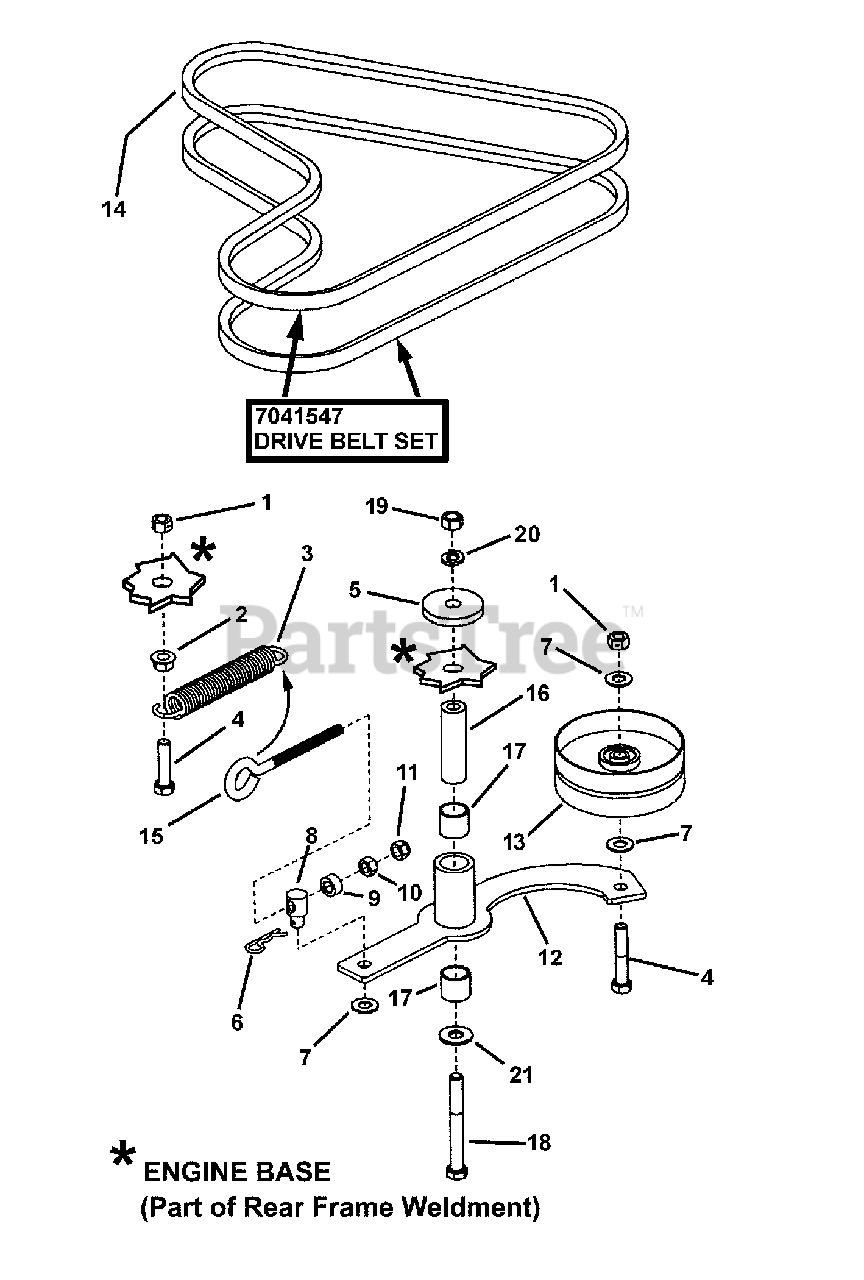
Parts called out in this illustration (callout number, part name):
1	NUT, 3/8-16 Hex Center Lock
2	NUT, 3/8-16 HEX SERRATED FLANGE
3	SPRING, Extension
4	SCREW, 3/8-16 x 1-1/2" Hex Head Cap, GR 5
5	WASHER, .468 x 1.85 x .25
6	HAIR PIN, 3/32 x 1-1/2"
7	WASHER, 3/8" Flat SAE
8	SWIVEL, Adjustable
9	SPACER, .340 I.D. x .63 O.D. x .310 Thick
10	NUT, 5/16-18 Hex, GR 5 or B
11	NUT, 5/16-18 HEX NYLON LOCK
12	WELDMENT, Idler Arm
13	PULLEY, 4" O.D. x .391 I.D. x 1.25 Backside Idler
14	BELT, Hydro Drive (HA Section, 47.5 Effective Length)
15	EYEBOLT, 5/16-18
16	BOSS, IDLER,YELLOW GV3036304
17	BUSHING, SLEEVE, 3/4 ID, GV3031224
18	BOLT, 3/8-16 x 3-1/2" Hex Head, GR 5
19	NUT, 3/8-16 Hex, GR 5 or B
20	WASHER, 3/8" Split Lock
21	WASHER, 3/8" USS
